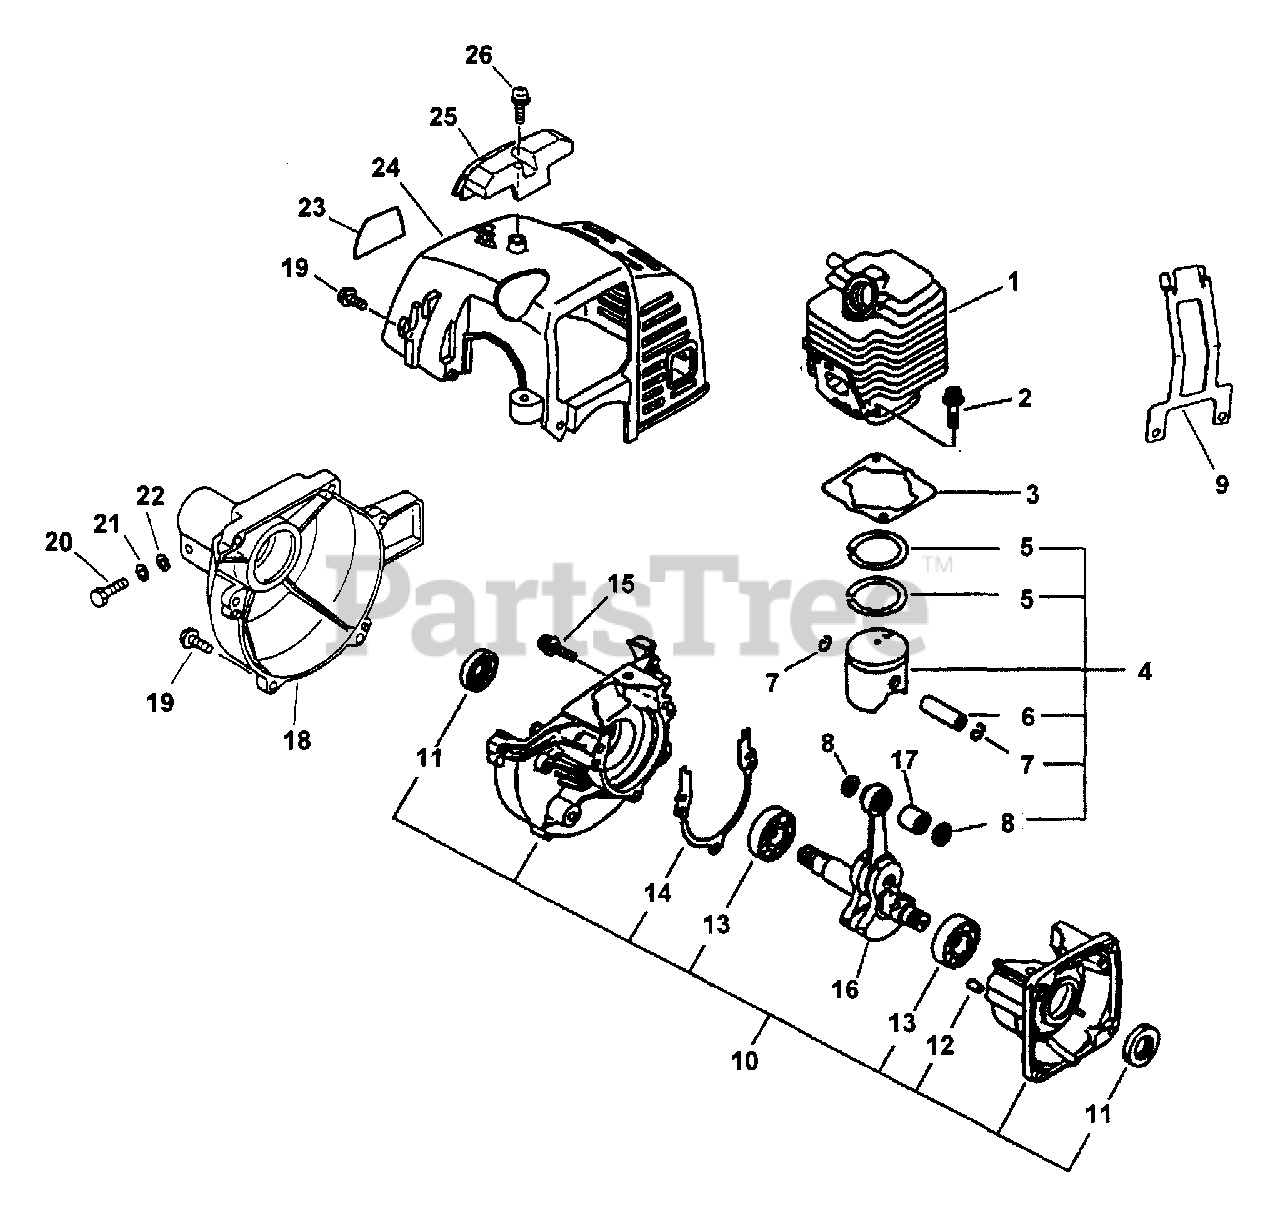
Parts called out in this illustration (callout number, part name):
1	CYLINDER
2	SCREW - 5X22
3	GASKET, CYLINDER
4	PISTON KIT
5	RING, PISTON
6	PIN, PISTON
7	RING, RETAINING
8	SPACER, PISTON
9	GUARD, ENGINE
10	CRANKCASE KIT
11	SEAL, OIL
12	PIN - LOCATING
13	BEARING, BALL - 6201
14	GASKET, CRANKCASE
15	SCREW - 5X28
16	CRANKSHAFT ASSY
17	BEARING, NEEDLE
18	CASE, FAN - ORANGE
19	SCREW - 4X16
20	BOLT - 5X25
21	LOCKWASHER - 5
22	WASHER - 5
23	LABEL - MODEL
24	COVER, ENGINE - ORANGE
25	GUARD, TOP - BLACK
26	SCREW - 5X16 -- TAPPING
